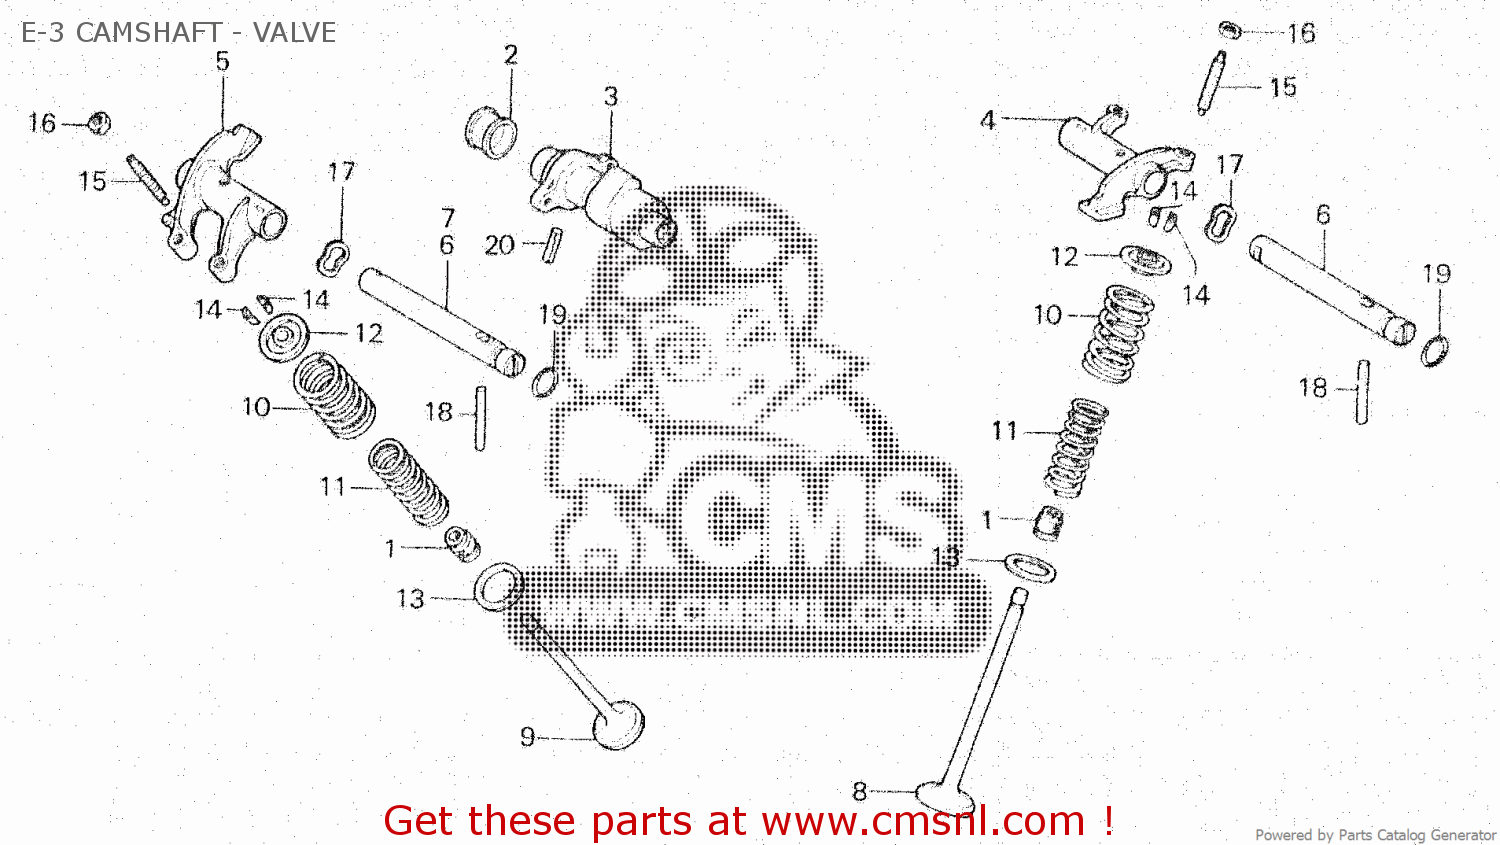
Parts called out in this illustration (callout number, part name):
1	SEAL,VALVE STEM
2	PLUG,CAMSHAFT
3	CAMSHAFT
4	ARM,IN,ROCKER
5	ARM,EX,ROCKER,
6	SHAFT,ROCKER ARM
8	VALVE,IN.
9	VALVE,EX.
10	SPG,VALVE,OUTER
11	SPG,VALVE,INNER
12	RET,VALVE SPG
13	SEAT,VALVE SPG
14	COTTER,VALVE
15	SCREW,TAPET
16	NUT, TAPPET ADJG.
17	WASHER,WAVE,12MM
18	PIN,DOWEL,5X33
19	O-RING,7.7X2.5
